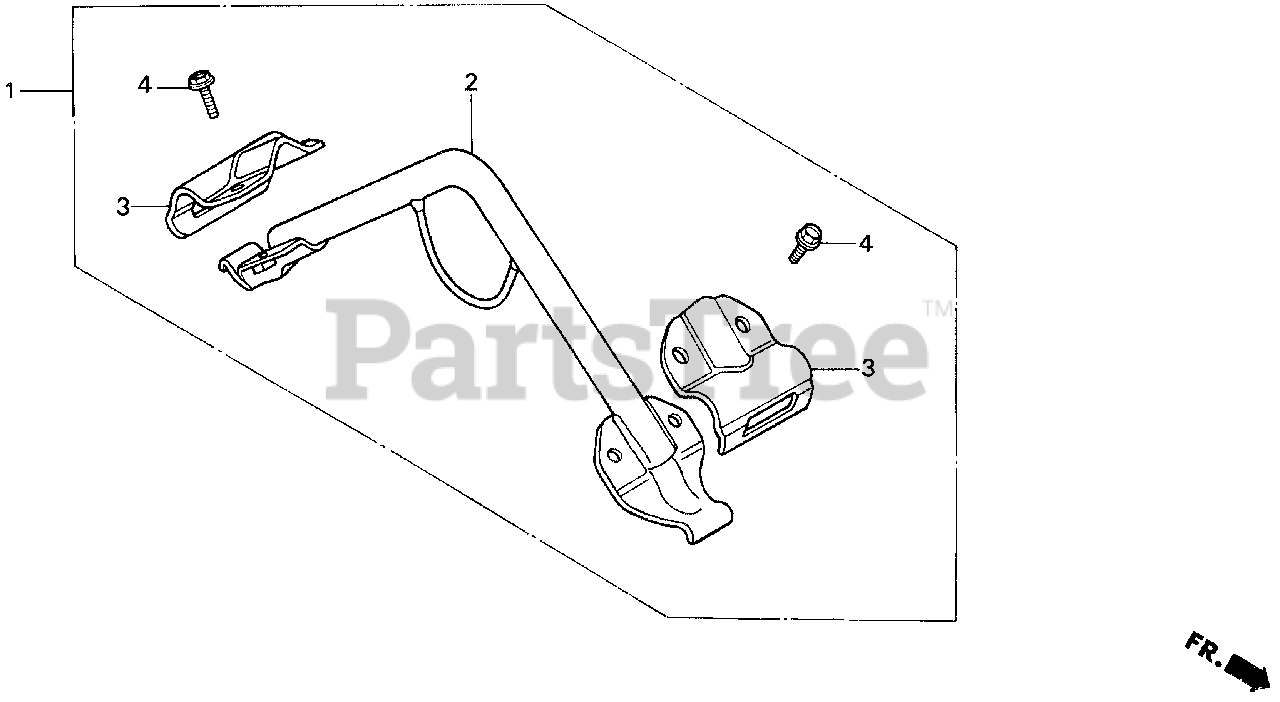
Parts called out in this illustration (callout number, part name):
1	HANGER KIT
3	BRACKET, HANGER (UPPER)
4	BOLT, FLANGE (8X16)
